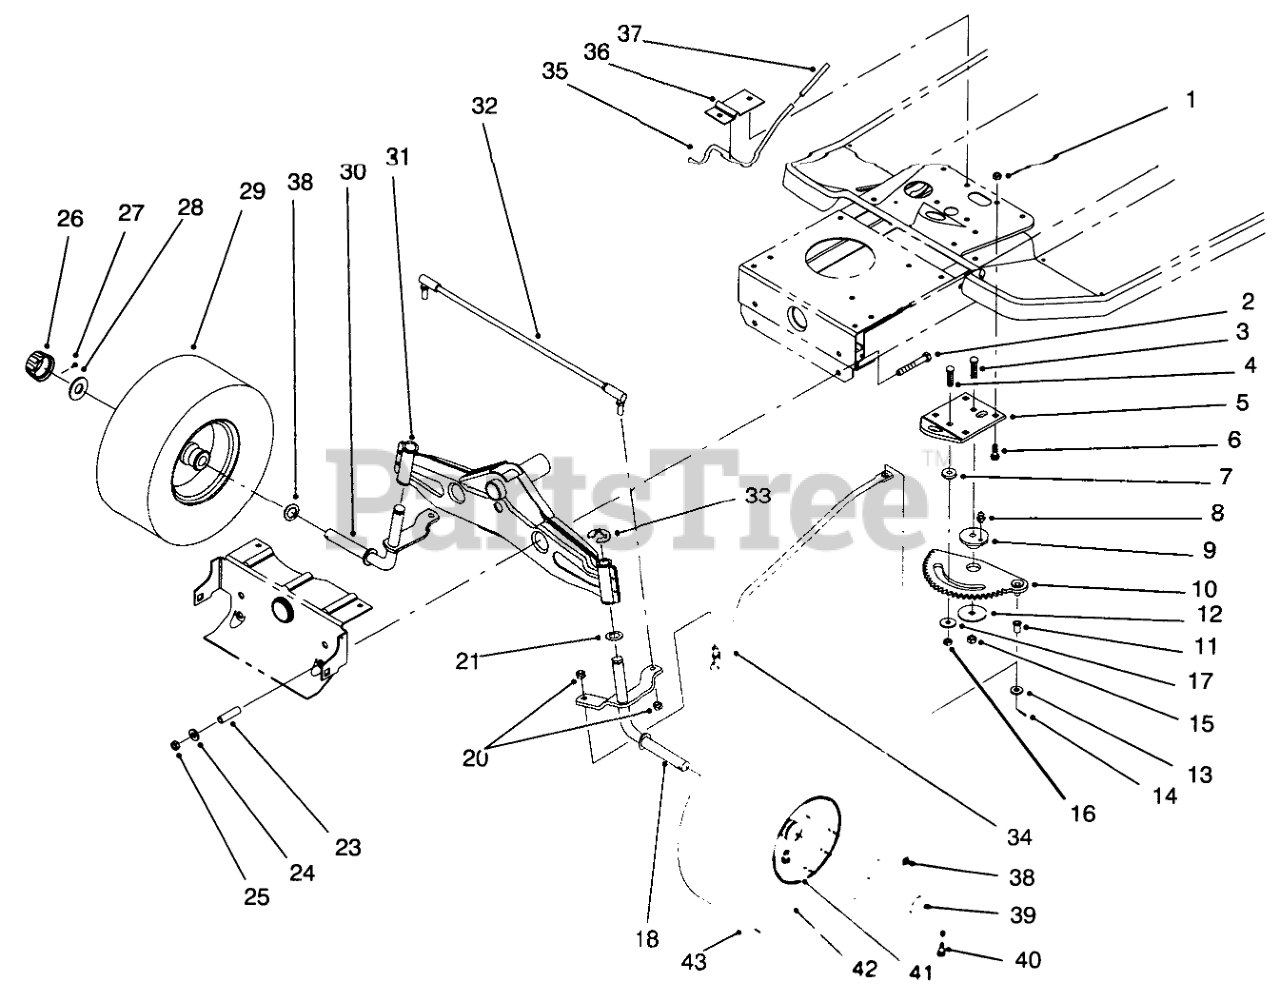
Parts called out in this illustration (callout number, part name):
1	NUT-LOCK, NI
2	SCREW-HH
3	SCREW-CARR
4	SCREW-CARR
5	Bracket-Steering Rack
6	BOLT-CARR
7	SPACER-RACK, STEERING
8	FITTING-GREASE
9	BUSHING-ECCENTRIC
10	RACK-STEERING
11	BUSHING-FLANGED, NYLON
12	WASHER-BEARING
13	WASHER-FLAT
14	PIN-COTTER
15	NUT-LOCK, NI
16	NUT-LOCK, NI
17	WASHER-PIVOT
18	Spindle-L.H.
20	NUT-HEX
21	WASHER-THRUST
23	SPACER
24	WASHER-FLAT
25	NUT-LOCK, NI
26	CAP-HUB
27	PIN-COTTER
28	WASHER-PLAIN
29:1	RIM ASM
29:2	TIRE 15 X 6.00 X 6
29:3	STEM-VALVE
29:4	BEARING-WHEEL
29:5	FITTING-GREASE
29:6	TUBE-INNER
30	Spindle-R.H.
31	Axle-Front
32	TIE ROD ASM
33	E-RING
34	LINK-DRAG
35	ROD-BRAKE, PARKING
36	Bracket-Parking Brake
37	GRIP-BRAKE, PARKING
38	WASHER-THRUST
